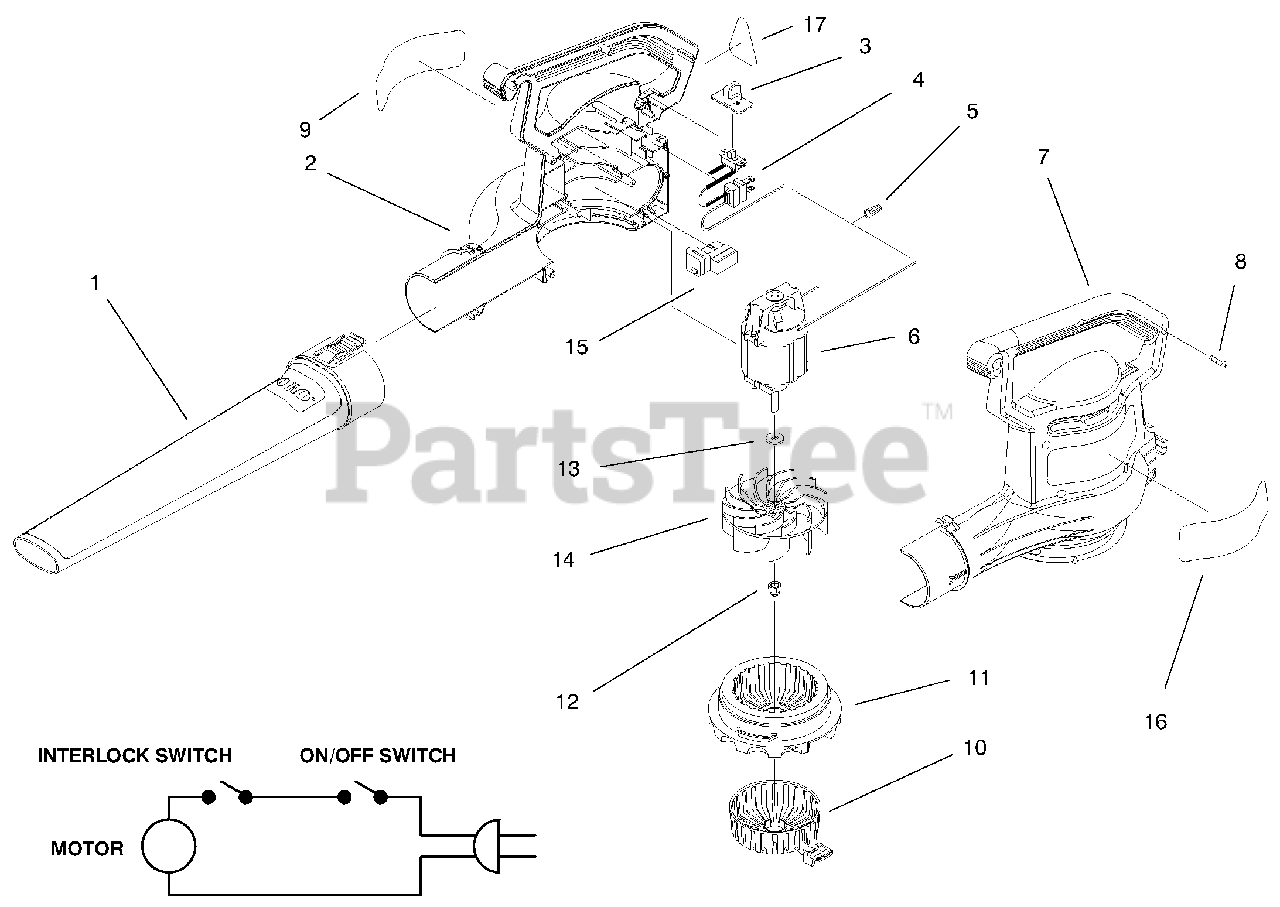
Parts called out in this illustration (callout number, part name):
1	Tube-Blower
2	Housing-R.H.
3	Cover-Switch
4	Harness Assembly
5	Connector-Wire Nut
7	Housing-L.H.
8	Screw-Phillips Hd. Tap.
9	Decal-Logo
10	Choke-Air
11	Cover-Inlet
12	Nut-Cap Hex
14	Impeller
15	Switch-Interlock
16	Decal-Warning
17	Decal-Information
